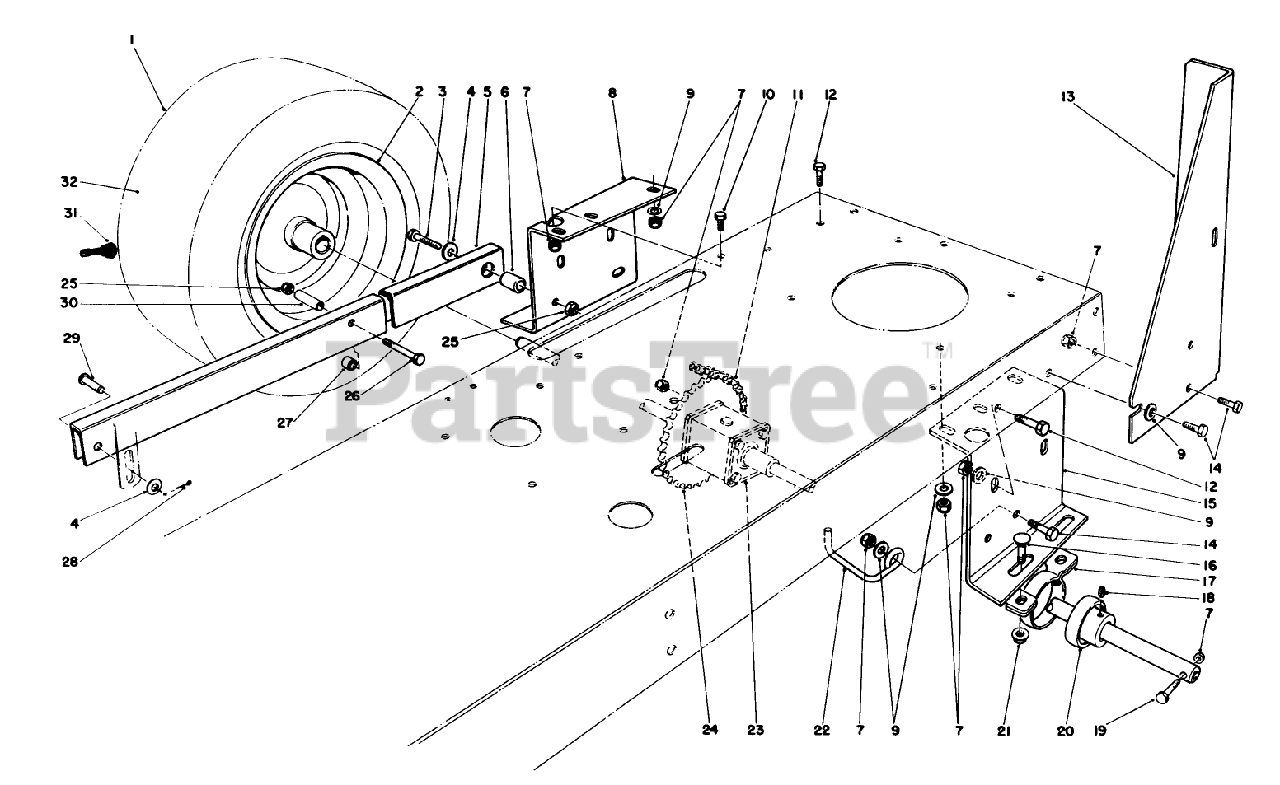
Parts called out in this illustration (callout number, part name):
3	SCREW-HH
4	WASHER-FLAT
6	SPACER
7	NUT-LOCK, NI
8	RH REAR AXLE SUPT *R
9	WASHER-PLAIN
10	SCREW-HH
11	ROLLER CHAIN
12	SCREW-HH
13	LH STANDBAR *B
14	SCREW-HH
15	LH REAR AXLE SU
16	SCREW-CARR
17	RTNR-PILLOW BLK
18	SCREW-SET, HSH
19	SCREW-HH
20	BEARING-BALL
21	NUT-HF
22	BELT GUIDE
24	42T DIFF SPROCKET
25	NUT-LOCK, CONE
26	SCREW-HH
27	INNER TUBE SPACER
28	PIN-COTTER
29	PIN-CLEVIS
32	TUBE-INNER
